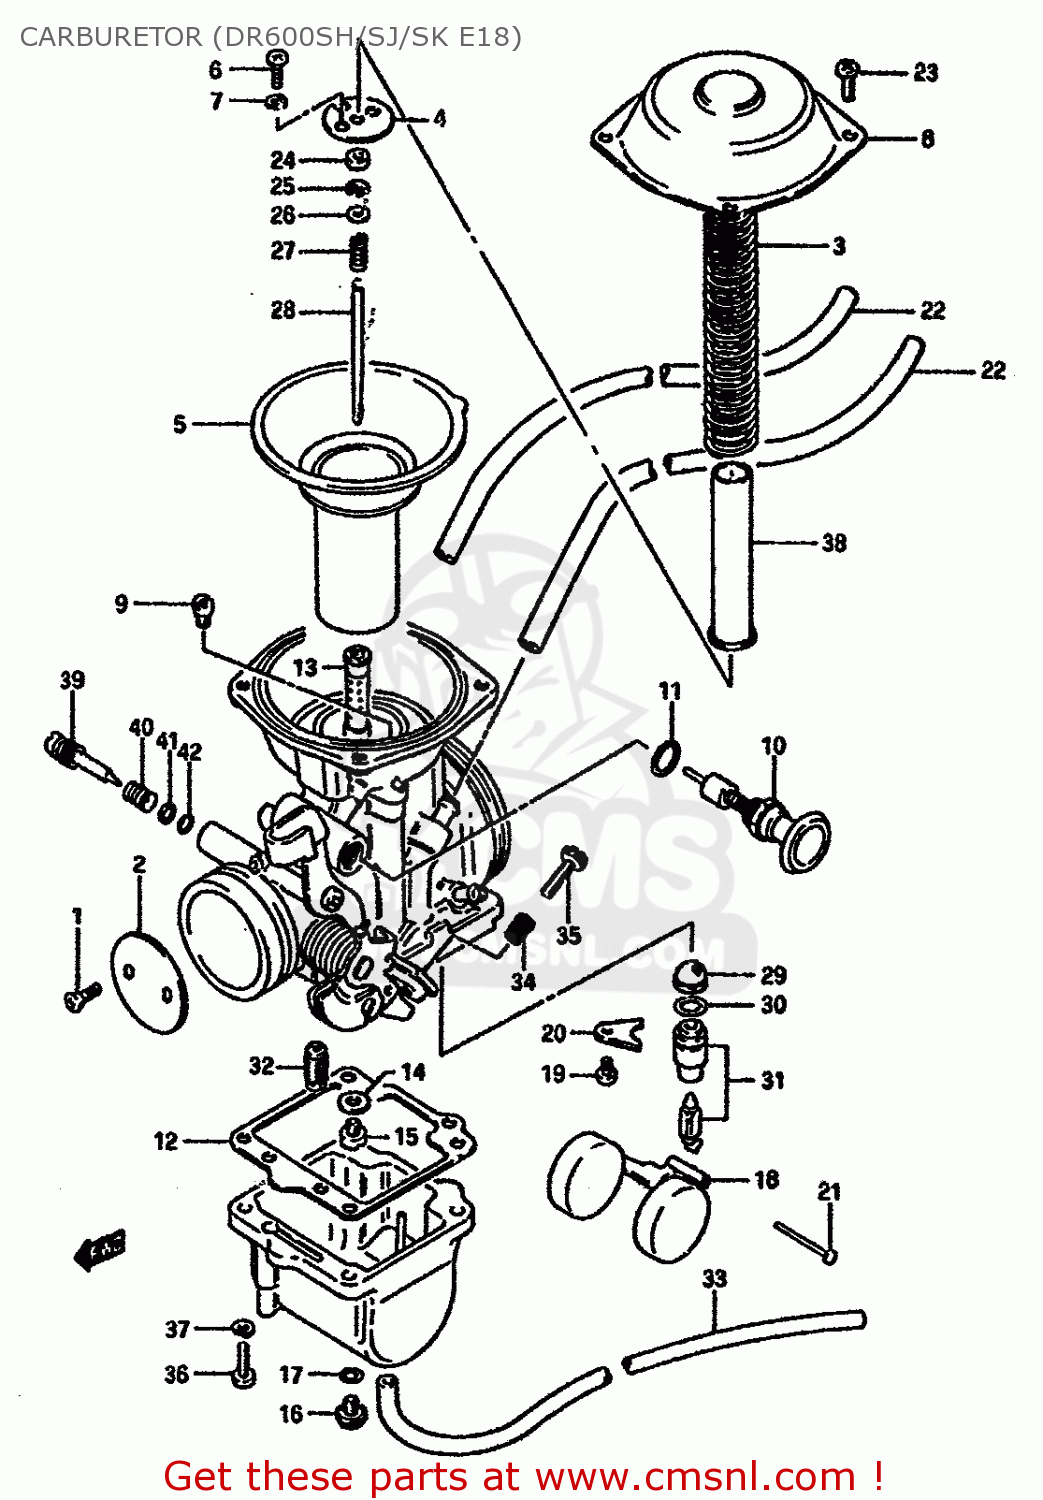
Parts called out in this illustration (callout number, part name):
1	SCREW
2	VALVE,THROTTLE (BUTTERFLY)
3	SPRING,DIAPHRAGM
4	PLATE
5	DIAPHRAGM ASSY
6	SCREW
7	LOCK WASHER
8	COVER
9	JET,MAIN(105)
10	PLANGER ASSY
11	O RING
12	GASKET,FLOAT CHAMBER (NAS)
13	JET,NEEDLE
14	WASHER,NEEDLE NOZZLE
15	JET,MAIN(142.5)
16	PLUG,DRAIN
17	GASKET (NAS)
18	FLOAT
19	SCREW
20	PLATE
21	PIN,FLOAT
22	HOSE
23	SCREW 5X10
24	RING
25	CLIP,NEEDLE
26	WASHER
27	SPRING
28	NEEDLE JET
29	FILTER
30	O-RING,NEEDLE VALVE
31	VALVE ASSEMBLY,NEEDLE
32	JET,PILOT(47.5)
33	HOSE
34	SPRING
35	SCREW,THROTTLE STOP
36	SCREW
37	LOCK WASHER
38	PIPE
39	SCREW,PILOT AIR
40	SPRING
41	WASHER
42	O RING,PILOT AIR SCREW
